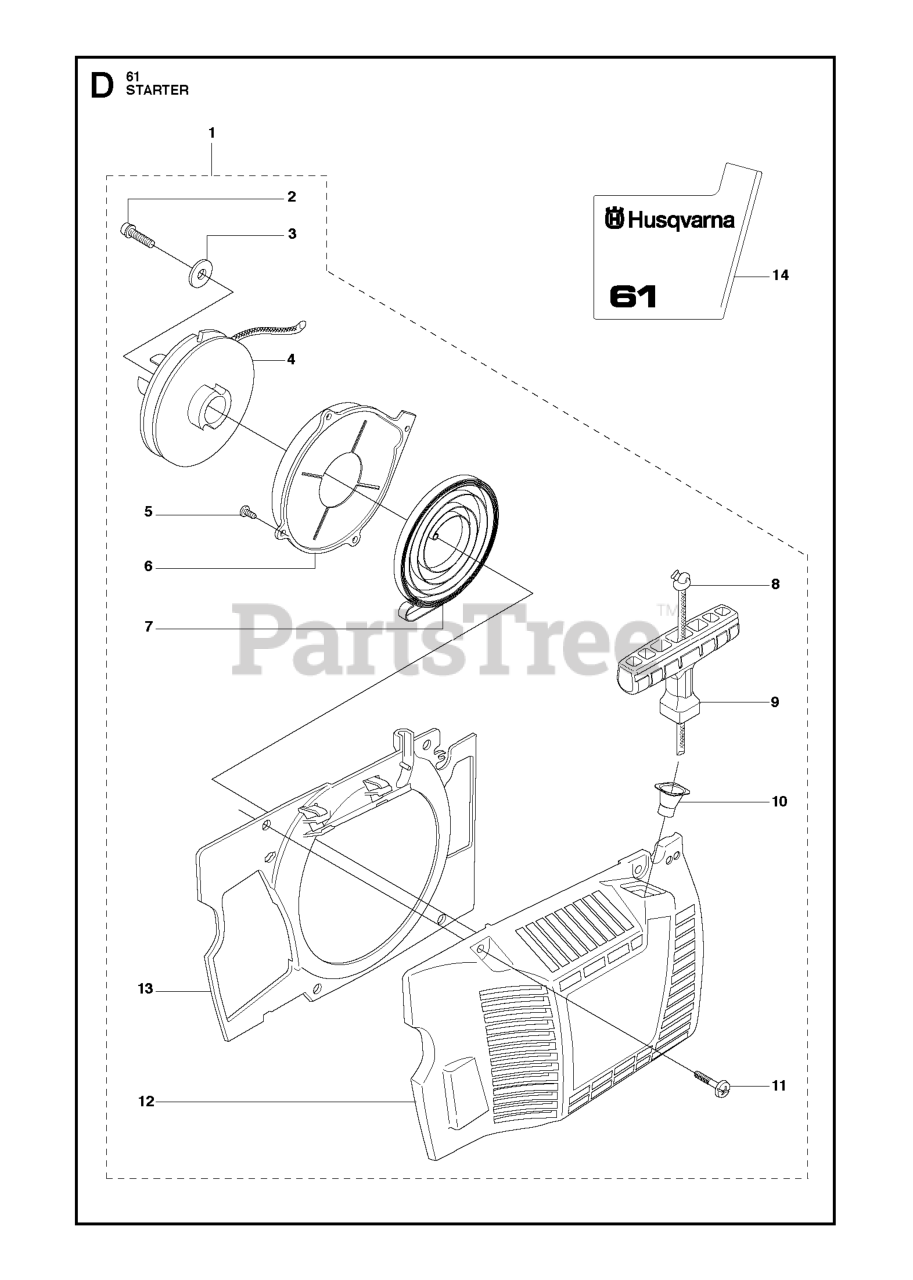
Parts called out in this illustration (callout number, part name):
1	STARTER DEVICE CPL
2	SCREW IHSCFT PW5.5X16 8.8 ZN/
4	STARTER PULLEY
7	RECOIL SPRING
8	STARTER ROPE
9	STARTER HANDLE
11	SCREW
12	STARTER HOUSING
13	AIR CONDUCTOR
14	DECAL STARTER
